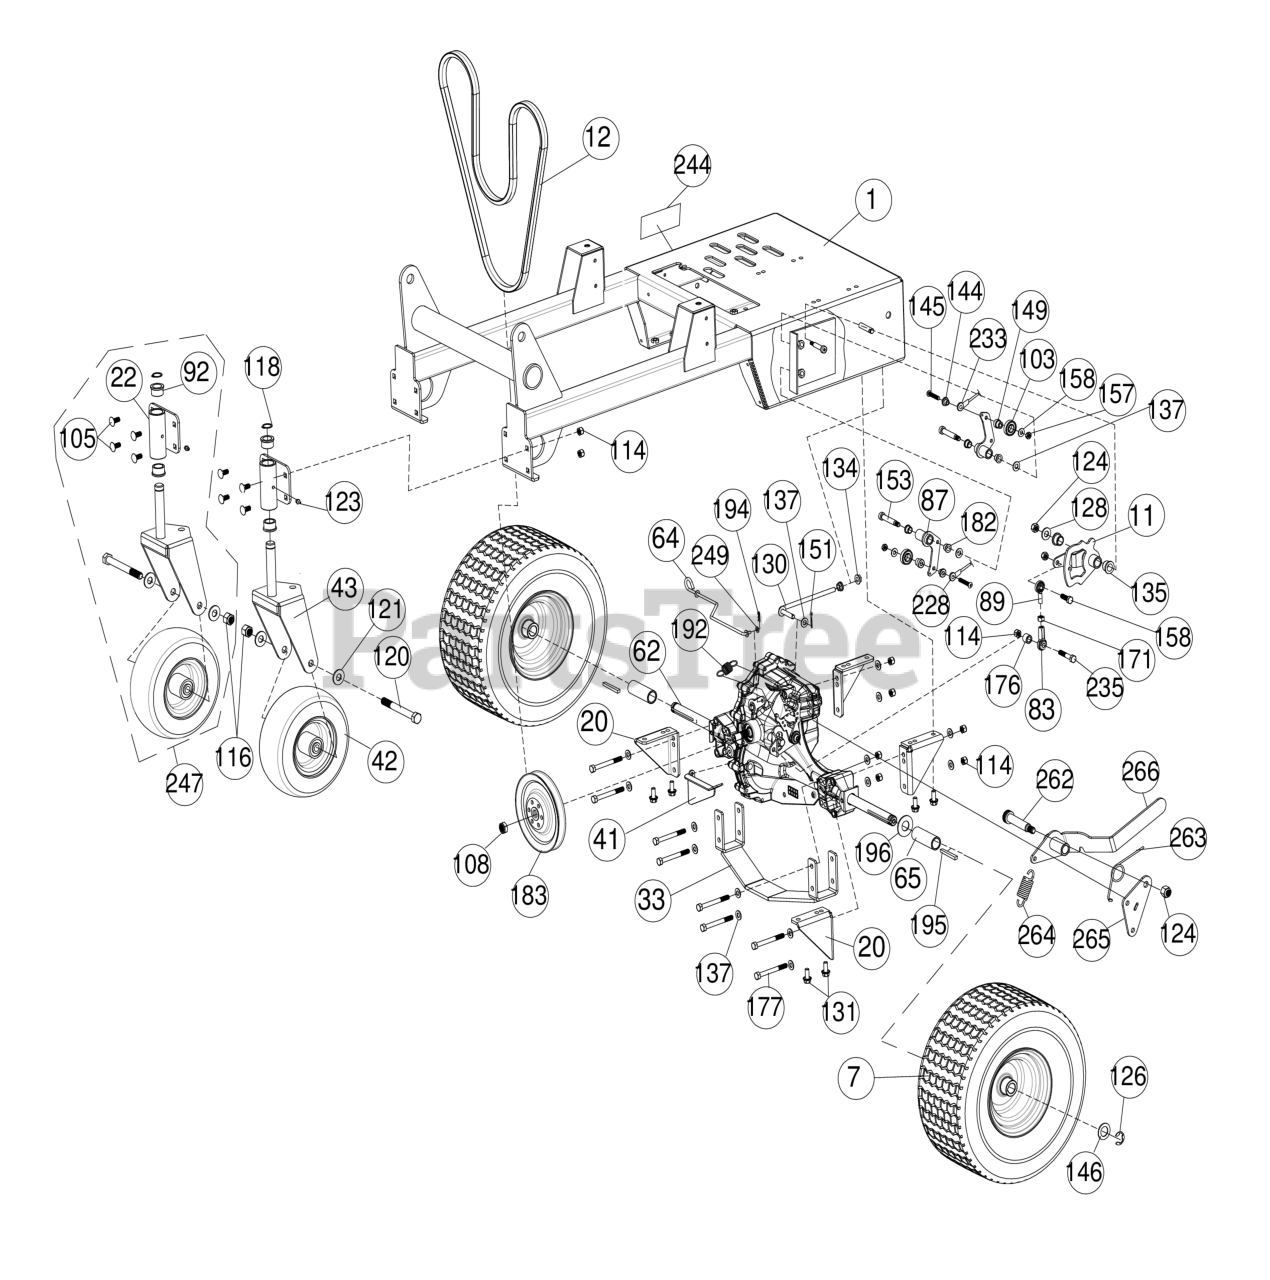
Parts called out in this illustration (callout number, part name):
1	SEE: 362602
7	WHEEL 15" X 6.00 - 6 TURF SAVER
11	CAM SPEED CONTROL WA AE900
20	BRACKET TRANSAXLE MOUNT
22	BRACKET CASTER WA AE900
33	SKID PLATE WA
41	BRACKET BELT GUIDE LOWER AE900
42	SEE: 373300
43	SEE: 371102-S
62	TRANSAXLE AE900
64	ROD BYPASS TRANSAXLE
65	SPACER REAL WHEEL AE900H
83	SPHERICAL ROD END MSF-5
87	BELLCRANK SPEED CONTROL BC26
89	SPHERICAL ROD END MSM-5
92	BUSHING FLANGE 1" OD 3/4" ID
103	BEARING 1/2" ID X 1.125 OD
105	BOLT CARRIAGE 5/16"-18 X 3/4" ZP
108	NUT 1/2"-20 JAM W/LOCK
114	NUT LOCK 5/16"-18 HEX Z/P
116	NUT LOCK 1/2"-13 HEX
118	RING RETAINING EXTERNAL 3/4"
120	SCREWCAP 1/2"-13 X 4 3/4 HCS ZP GR. 5
121	WASHER 1/2" SAE Z/P
123	ZERK FITTING GREASE
124	NUT LOCK 3/8"-16 HEX
126	RING RETAINING "E" 3/4"
128	WASHER 5/16" FLATWASHER Z/P
130	ANTI ROTATION ROD
131	SER HEX WASHER FLNG SCREW 5/16"-18 X 3/4"
134	NUT FLANGE 5/16"-18 ZP
135	BUSHING .500" ID
137	WASHER 5/16" SAE Z/P
144	SPACER, SPEED CONTROL EYELET PM
145	SCREWCAP 1/4"-20X1 1/2" HCS ZP
146	WASHER .765" ID X 1.25 OD X .06"
149	SPACER. SPEED CONTROL STEPPED PM
151	PIN COTTER 1/8" X 1" Z/P
153	BOLT SHOULDER 3/8" X 1 3/4"
157	NUT LOCK, 1/4-20 LT WT TH ZP
158	SCREWCAP 5/16"-18 X 1" HCS ZP
171	NUT 5/16"-18 FIN HEX Z/P
176	SPACER ENGINE SIDE
177	SCREWCAP 5/16"-18 X 3" HCS ZP
182	BUSHING 3/8 ID X 1/2 OD X 3/8
183	PULLEY DIA. 6.00 CUPPED 26 TOOTH SPLINE
192	SPRING, TRANSAXLE RTN
194	PIN CLIP HITCH 0.051 X 3/4"
195	KEY 3/16" SQ X 3.00
196	WASHER 3/4" SAE 13/16"X1.5"X1/8"ZP
235	SCREWCAP 5/16"-18X1 1/2" HCS ZP
244	LABEL DRIVE RELEASE
247	CASTER ASSY AE1300H SERVICE
249	WASHER #10SAE 7/32"X1/2"X1/16"
262	BOLT SHOULDER 1/2" X 2"
263	SPRING TRANS IDLER
264	EXTENSION SPRING
265	PARKING BRAKE BRACKET
266	PARKING BRAKE LEVER
